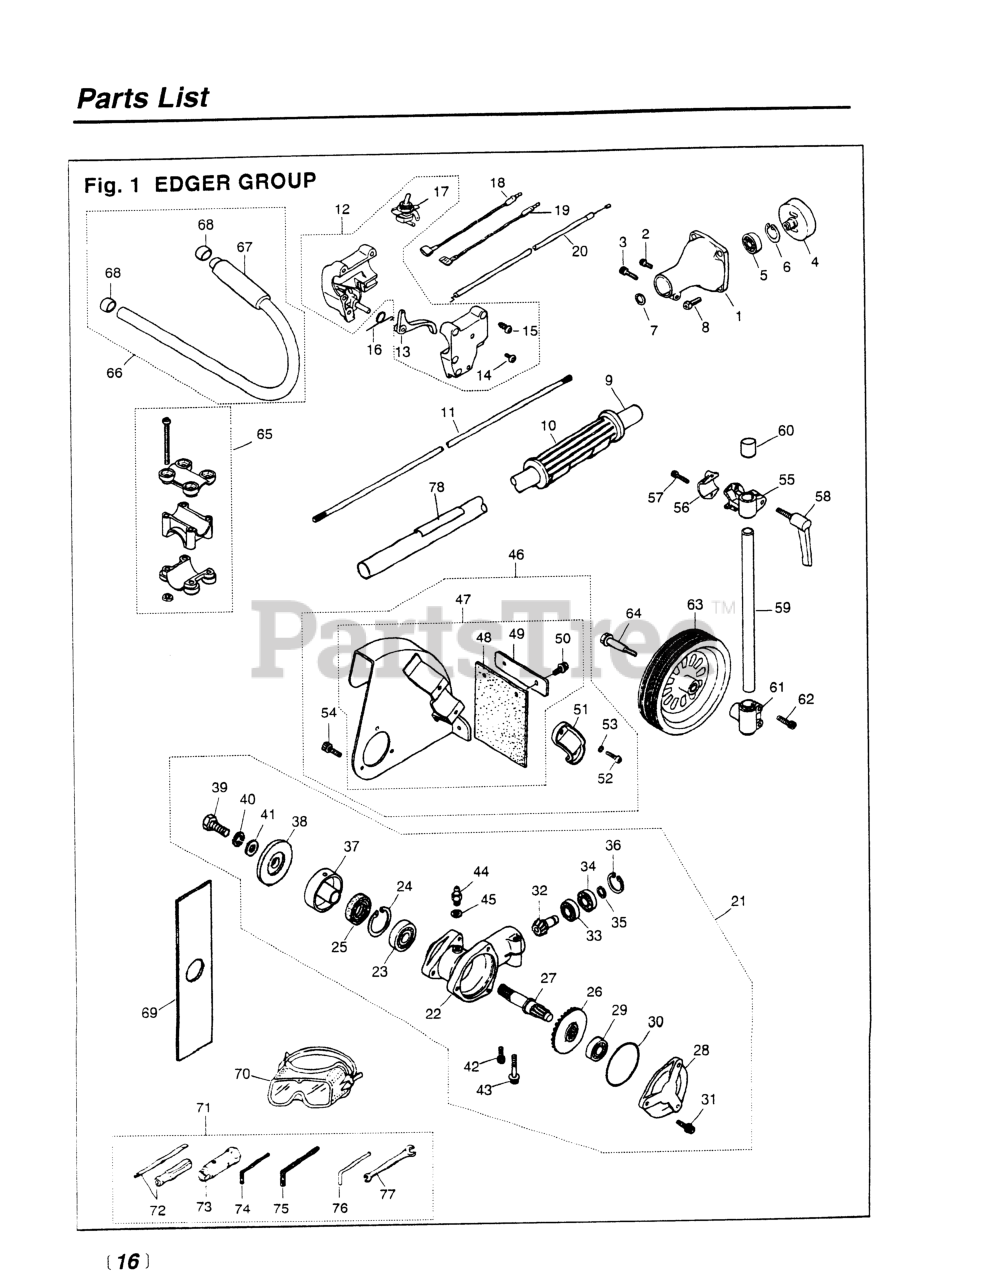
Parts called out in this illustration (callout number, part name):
2	BOLT, M5 X 10
3	BOLT, M5 X 25
5	BEARING
6	RING, SNAP, M28 x 1.2
8	BOLT, M6 x 20
13	LEVER, THROTTLE
14	SET SCREW, ANTI-ROTATION
15	SCREW
16	SPRING, THROTTLE TRIGGER
17	SWITCH, STOP
18	CORD, RED (LEAD WIRE)
19	CORD, BLACK (LEAD WIRE)
20	CABLE COMP (RPLS 6460- )
21	GEARCASE ASSEMBLY
22	GEARCASE
24	RING, SNAP, M32 x 1.2
25	SEAL, OIL
26	GEAR
27	SHAFT, GEAR
28	COVER
29	BEARING (RPLS T3403-13510)
30	O-RING
31	BOLT
32	PINION
33	BEARING (RPLS T3403-13530)
34	BEARING (RPLS T3300-13531)
35	RING, SNAP (RPLS T3300-13330)
36	RING, SNAP, M26 X 1.2
37	HOLDER (A)
38	HOLDER (B)
39	BOLT, LH
40	WASHER (RPLS 3180-13270)
41	WASHER, M8 x 2.3 (RPLS -20823)
42	BOLT, M5 X 10
43	BOLT, M6 x 1.35
44	FITTING, GREASE
45	WASHER, M6 X .8
48	PLATE (RUBBER)
49	PLATE (REPLACES -24130)
50	BOLT, M5 X 12
51	CLAMP
52	BOLT, M6 X 18
53	WASHER, M6 X 15
54	BOLT
55	BRACKET (NLA)
57	BOLT, M5 X 22
58	LEVER
59	TUBE, EDGER
60	CAP
61	BRACKET (NO LONGER AVAILABLE)
62	BOLT, M6 X 25
63	WHEEL, EDGER
64	BOLT
65	HANDLE BRACKET ASSEMBLY
66	J-HANDLE ASSEMBLY
67	GRIP, HANDLE
68	CAP
70	GOGGLE
71	TOOL SET
72	SCREWDRIVER
74	WRENCH (TOOL)
75	WRENCH (TOOL)
76	BAR
77	SPANNER, 8 X 10 (RPLS 2540- )
